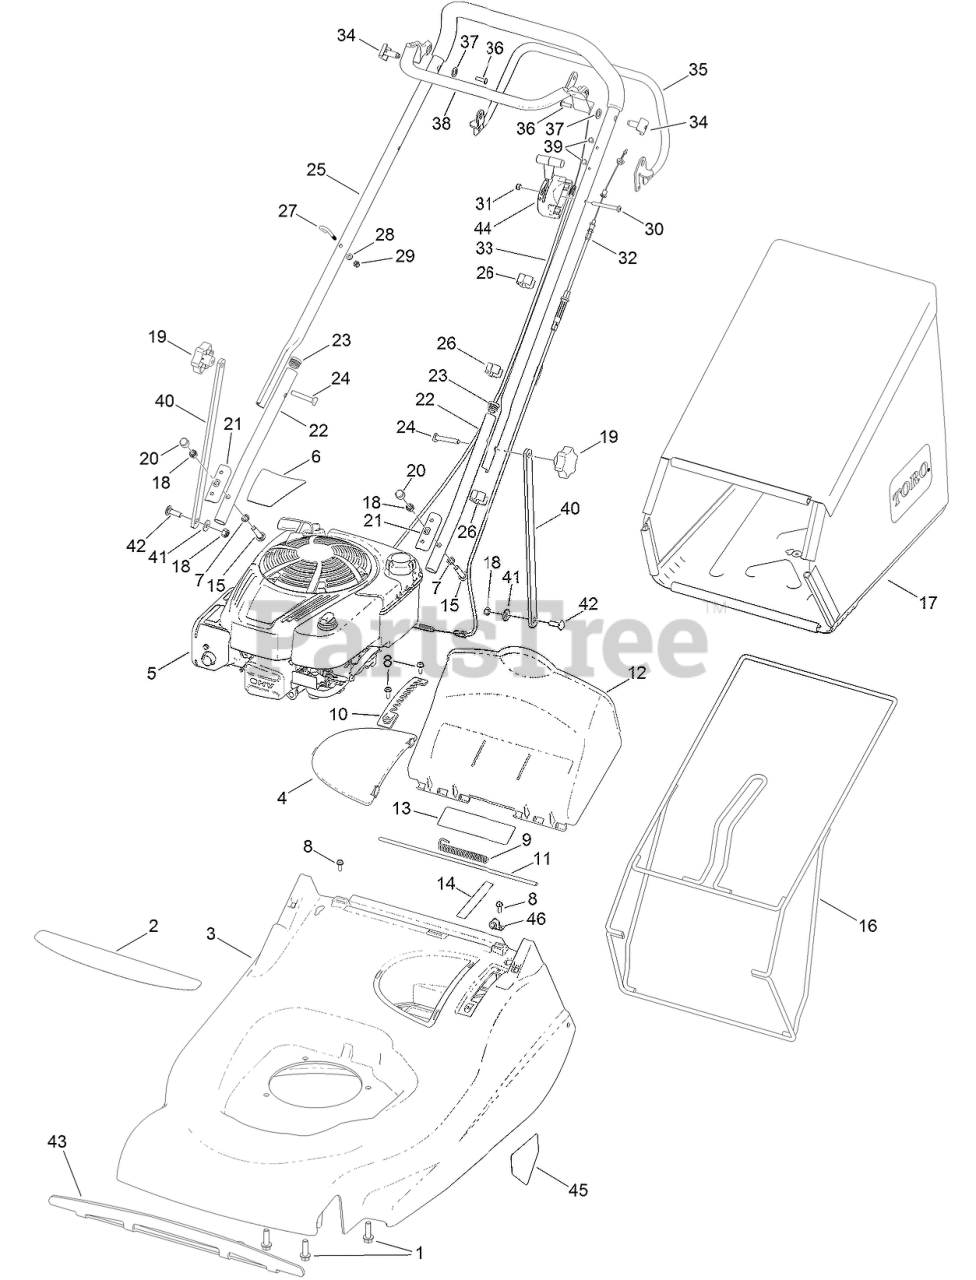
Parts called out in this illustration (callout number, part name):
1	SCREW-TAPTITE, UNC
2	DECAL-DECK
4	COVER-BATTERY
5	ENGINE-BRIGGS, 121Q020130F1
6	DECAL-ENGINE
7	GRIP-FIX
8	SCREW-TAPTITE
9	SPRING-DEFLECTOR
10	RATCHET-PLATE, HOC
11	ROD-DEFLECTOR
12	DEFLECTOR-REAR
13	DECAL-SAFETY
14	DECAL HOC
15	BOLT-COACH
16	FRAME-GRASSBAG
17	GRASSBAG-TORO
18	NUT-HEX, NI
19	KNOB-HANDLEBAR
20	CAP-NUT
21	PLATE-CLAMP, HANDLEBAR
22	HANDLEBAR-LOWER
23	PLUG-TUBE
24	BOLT
25	HANDLEBAR-UPPER
26	GUIDE-CABLE
27	GUIDE-ROPE
28	WASHER-PLAIN
29	NUT-NYLOC
30	SETSCREW
31	NUT-NYLOC
32	CABLE-ENGINE, BRAKE
33	CABLE-CLUTCH
34	PIN-PIVOT
35	LEVER-CLUTCH
36	SCREW
37	WASHER-NYLON
38	LEVER-ENGINE
39	FASTENER-DRIVE
40	BRACE-HANDLEBAR
41	WASHER
42	BOLT-COACH
43	BAR-BUMP, PLATE
44	CONTROL-SPEED, ENGINE
45	DECAL-DANGER
46	CLIP-CABLE
